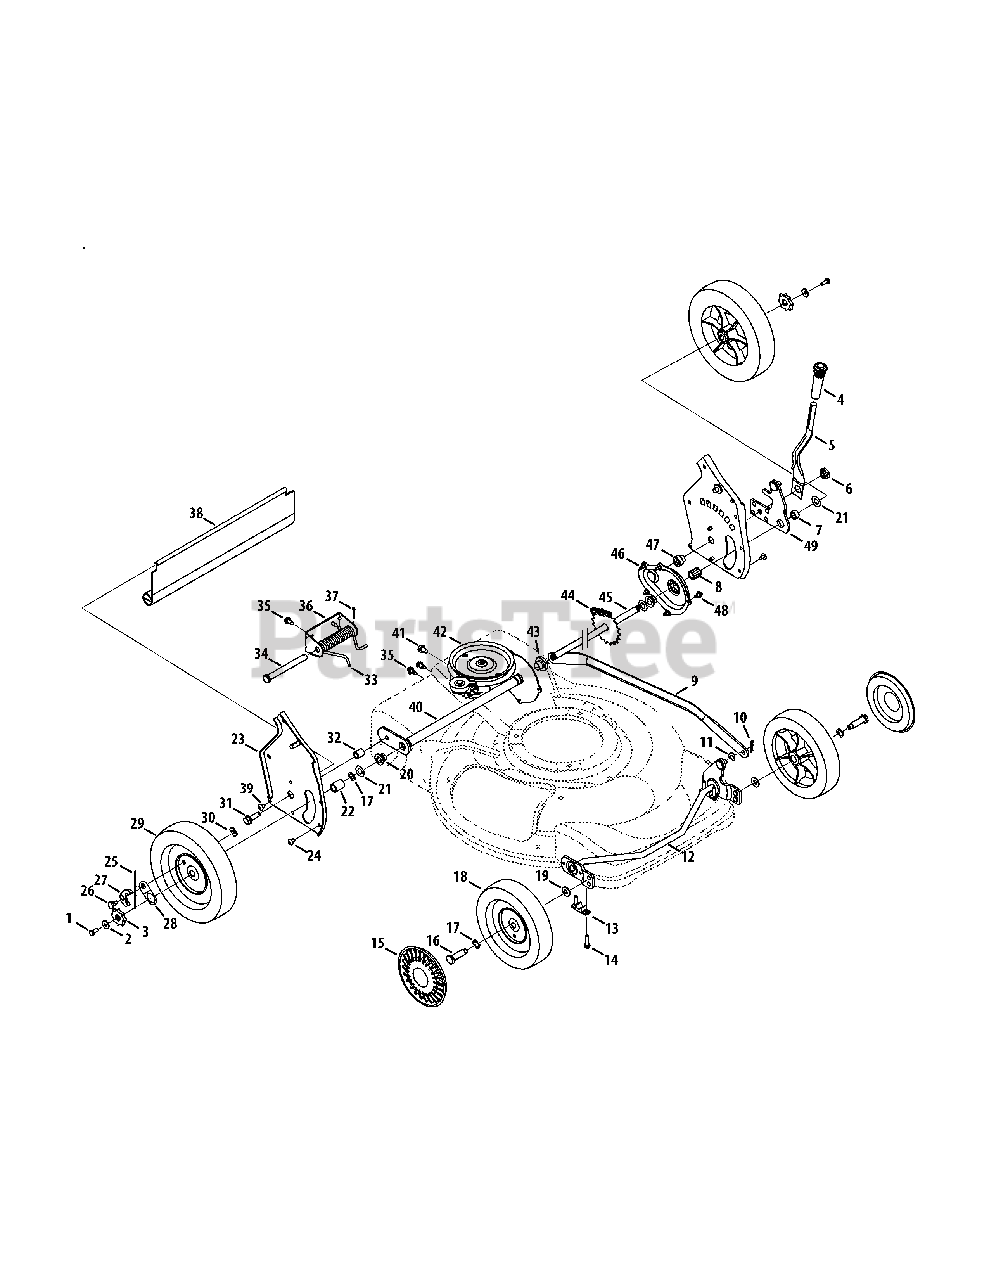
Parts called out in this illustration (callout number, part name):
1	HH Cap Screw 1/4-20 x .620
2	Bell Washer .265 x .75 x .062
3	Wheel Ratchet
5	Spring Lever
6	Shoulder Nut
7	Spacer .51 x .70 x .38
8	Hex Sleeve Bearing
9	Single Lever Control Arm
10	Hairpin Clip
11	Bowed Washer
12	Front Axle Assembly
13	Block Bushing
14	Hex Screw 1/4-15 x 1
16	Shoulder Scr., .498x1.445x3/8-16
17	Wave Washer .510 x .750 x .017
18	Front Wheel 8 x 2.125 COG
19	Bell Washer .375 x .870 x .063
20	Hex Flange Bearing
21	Flat Washer .508 x 1 x .020
22	Spacer .550 x .755 x 1.1
23	Handle Bracket Assy RH
23	Handle Bracket Assy LH
24	AB Screw 1/4-14 x .50
25	Plastic Ratchet Spring
26	Shoulder Scr., .340x.285x1/4-20
27	Pawl - RH
28	Ratchet Pawl Plate
29	Rear Wheel 9 x 2.125 Rwd PM
30	Weld Nut
31	TT Screw 3/8-16 x 1.25
32	Spacer .385 x .625 x .700
33	Torsion Spring RH
34	Clevis Pin .500 x 4.62
35	TT Screw 1/4-20 x .625
36	Lift Assist Spring Bracket
37	Cotter Pin
38	Trail shield
39	AB Screw, #10-16 x .500
40	Transmission Axle Assembly
41	TT Screw 5/16-18 x .625
42	Transmission
43	Hex Flange Bearing
45	Axle Assembly RR
46	Chain Cover Assembly
47	Shoulder Spacer .385 x .715
48	TT Screw, 1/4-20 x .375
49	RR Pivot Arm Assembly
